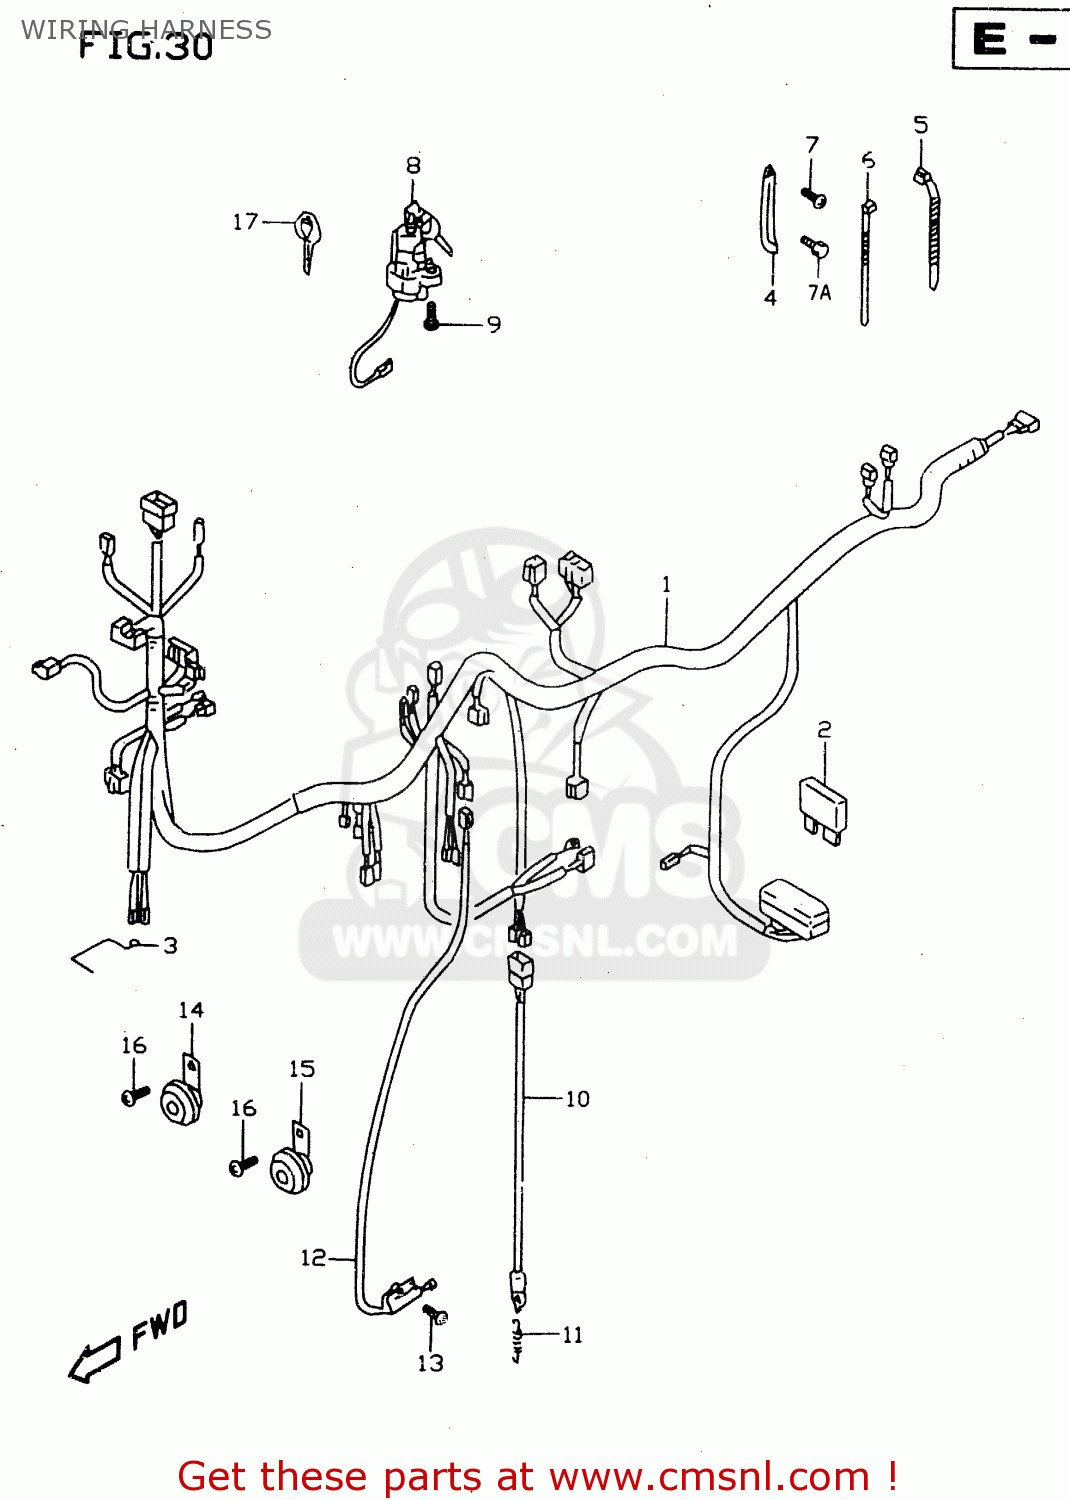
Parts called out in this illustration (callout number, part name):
1	HARNESS,WIRING
2	FUSE(10A)
3	GUIDE,HARNESS
4	CLAMP(L:65)
5	CLAMP(L:125)
6	CLAMP(L:145)
7	SCREW 6X12
7A	BOLT
8	LOCK ASSY,STEERING
9	BOLT(8X20)
10	SWITCH ASSY,STOP LAMP
11	SPRING
12	SWITCH ASSY,SIDE STAND
13	SCREW
14	HORN ASSY
15	HORN ASSY,HIGH PITCHED
16	BOLT
17	KEY,BLANK
